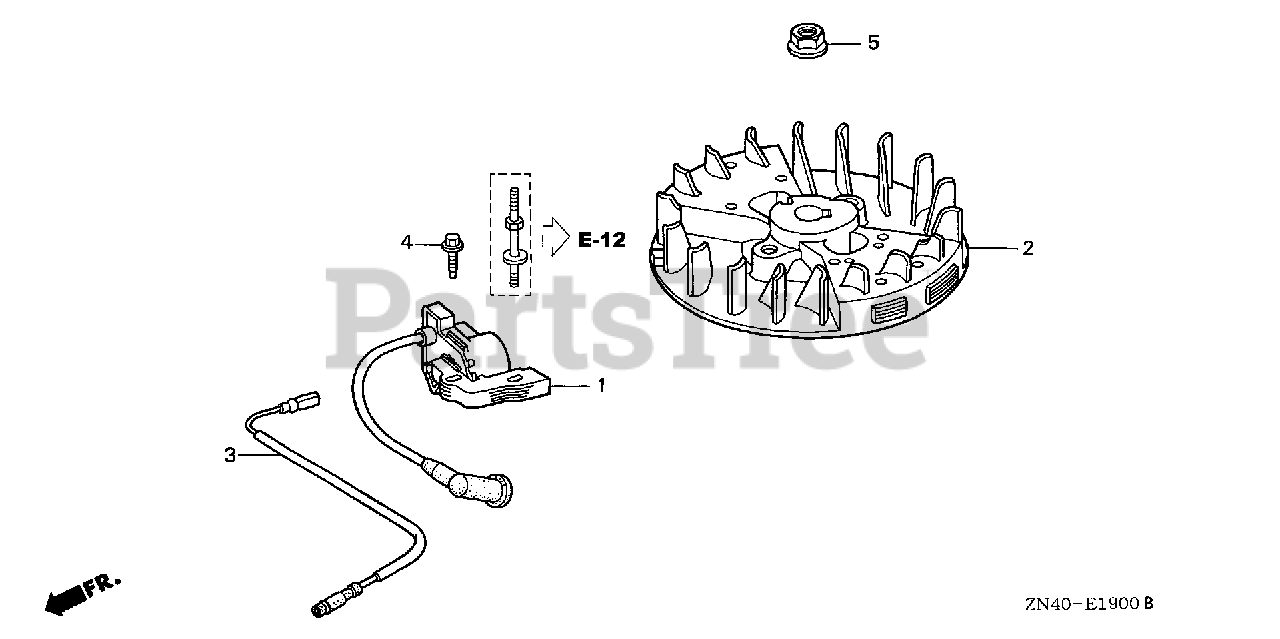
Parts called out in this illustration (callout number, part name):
1	COIL ASSY., IGNITION
3	WIRE, STOP SWITCH
4	BOLT, FLANGE (5X20)
5	NUT, FLANGE (10MM)
